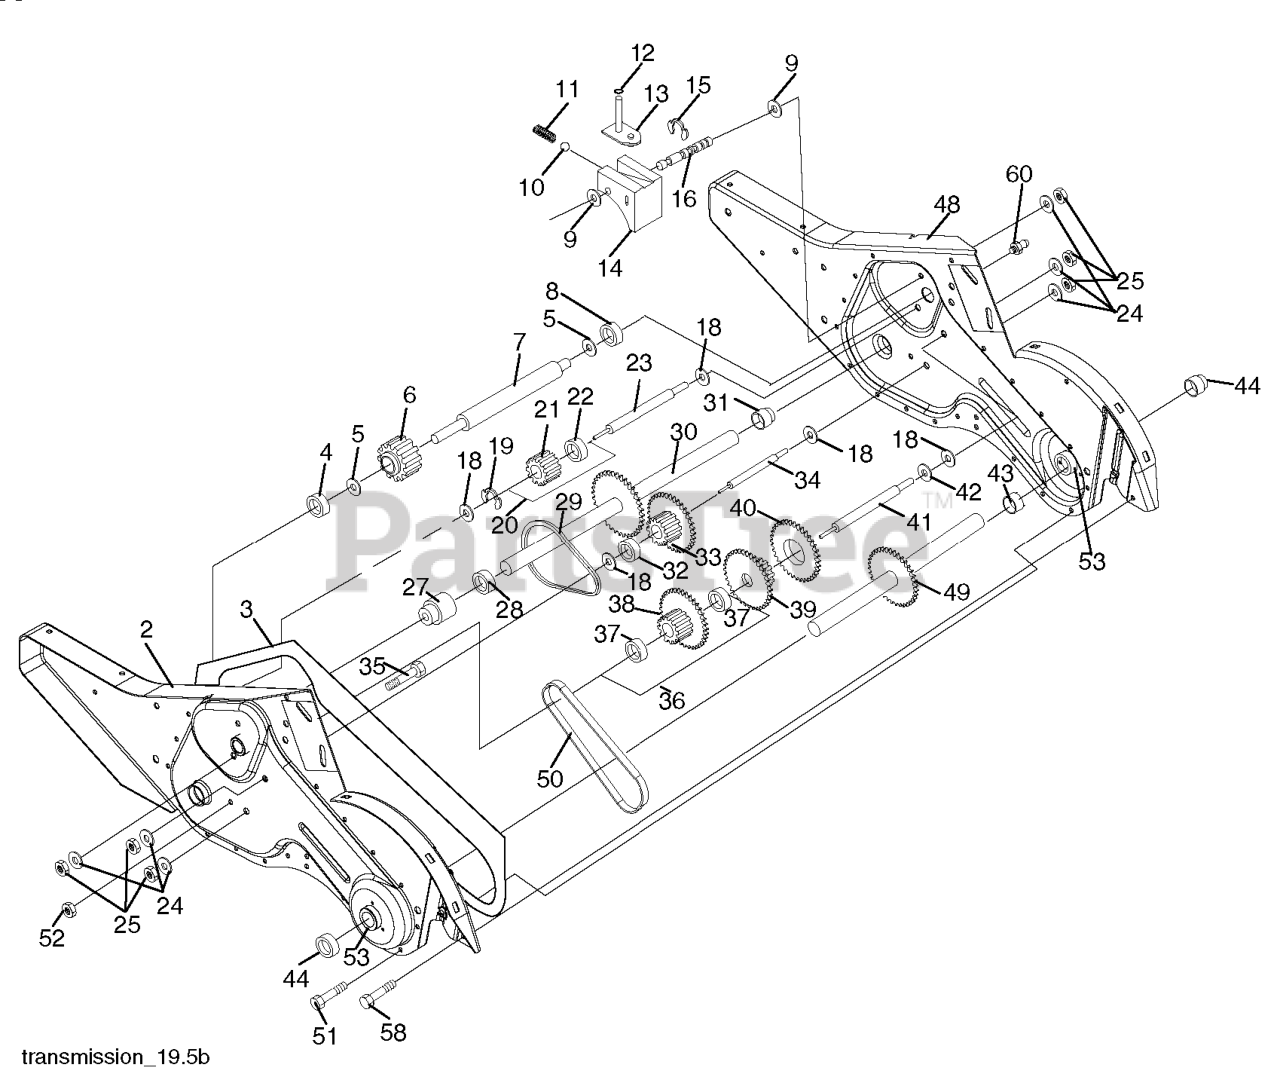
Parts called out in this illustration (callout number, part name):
1	TRANSMISSION ASM.
2	GEARCASE.ASM.CRT.LH.W/BEARING
3	GASKET
4	NEEDLE BRNG LT
5	THRUST WASHER
6	GEAR.PINION.INPUT
7	SHAFT.INPUT."D".TILLER
8	BEARING TI
9	WASHER, SEAL (2 2)
10	STEEL BALL KIT
11	SPRING-SHIFT CRT
13	BRACKET ASM.SHIFT.CRT
14	SHIFT FORK TI
16	SHAFT.SHIFTER.TILLER
20	GEAR ASSY CRT
21	GEAR-REV IDLR CRT
22	NEEDLE BEARING TI
24	LOCKWASHER
25	NUT.ASF.HEX.7/16
27	BEARING, SHAFT LH CRT
30	GROUND SHAFT ASS'Y
31	BEARING, SHAFT RH CRT
33	SPRCKT 8 GEAR CRT
34	SHAFT.SECONDARY.REDUCTION.CRT
35	SCRW WHIZ LOK CRT
36	SPROCKET.ASM.W/BEARING.TILLER
37	BEARING
38	SPROCKET, TINE
41	SHAFT.REDUCTION.TILLER
42	BRNG RACE T
44	SEAL ASM, OIL
48	GEARCASE.ASM.CRT.RH.W/BEARING
49	TINE SHAFT
50	CHAIN.TILLER
51	SCREW
52	NUT
53	KIT.BEARING.TILLER.
58	BOLT SHOULDER 1/4-20 UNC X.875
60	FITTING.GREASE.TAPERED
